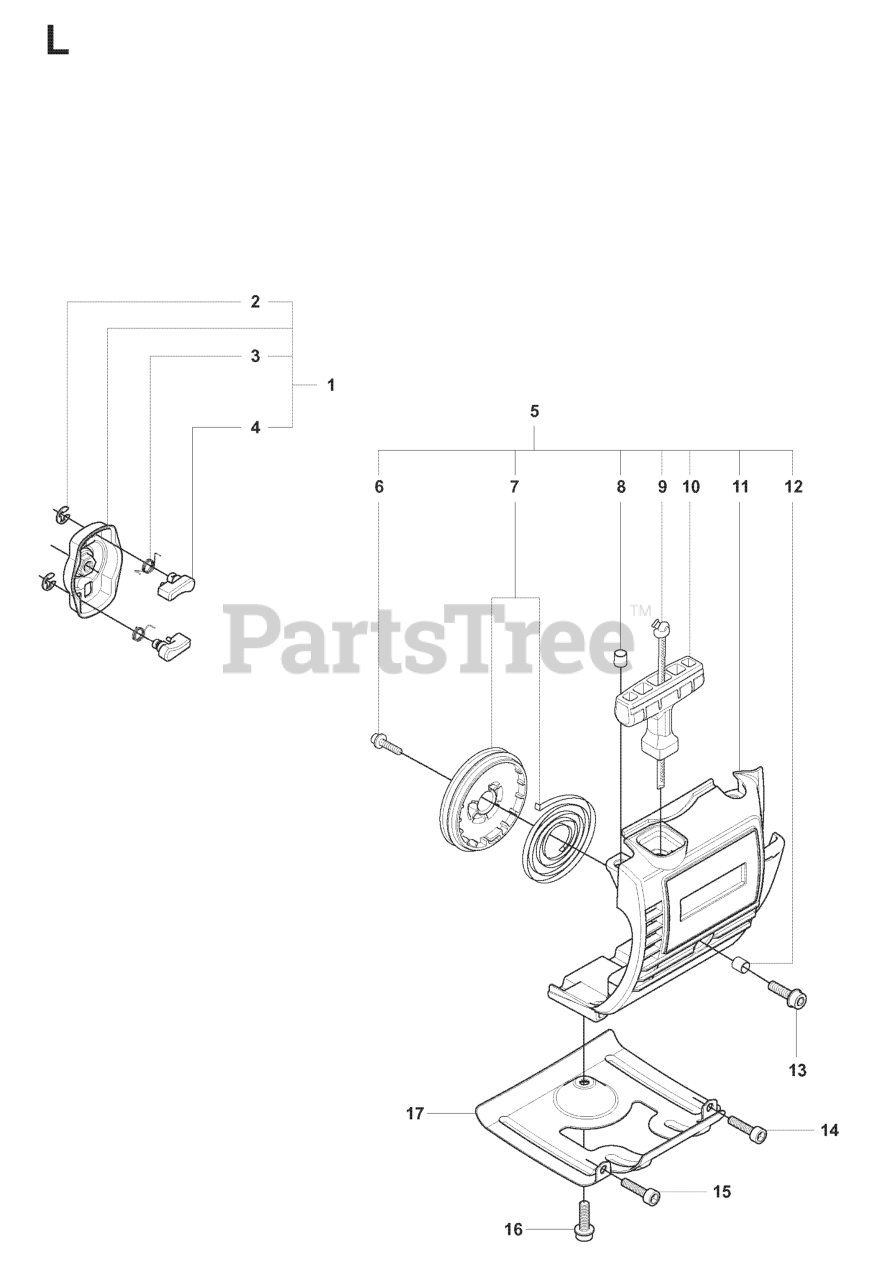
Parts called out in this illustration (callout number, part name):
1	STARTER PAWL BRIDGE
4	STARTER PAWL
5	STARTER ASSY
7	STARTER PULLEY ASSY.
8	SPACING SLEEVE
9	STARTER ROPE
10	STARTER HANDLE
11	RP STARTER HOUSING
12	SPACING SLEEVE
